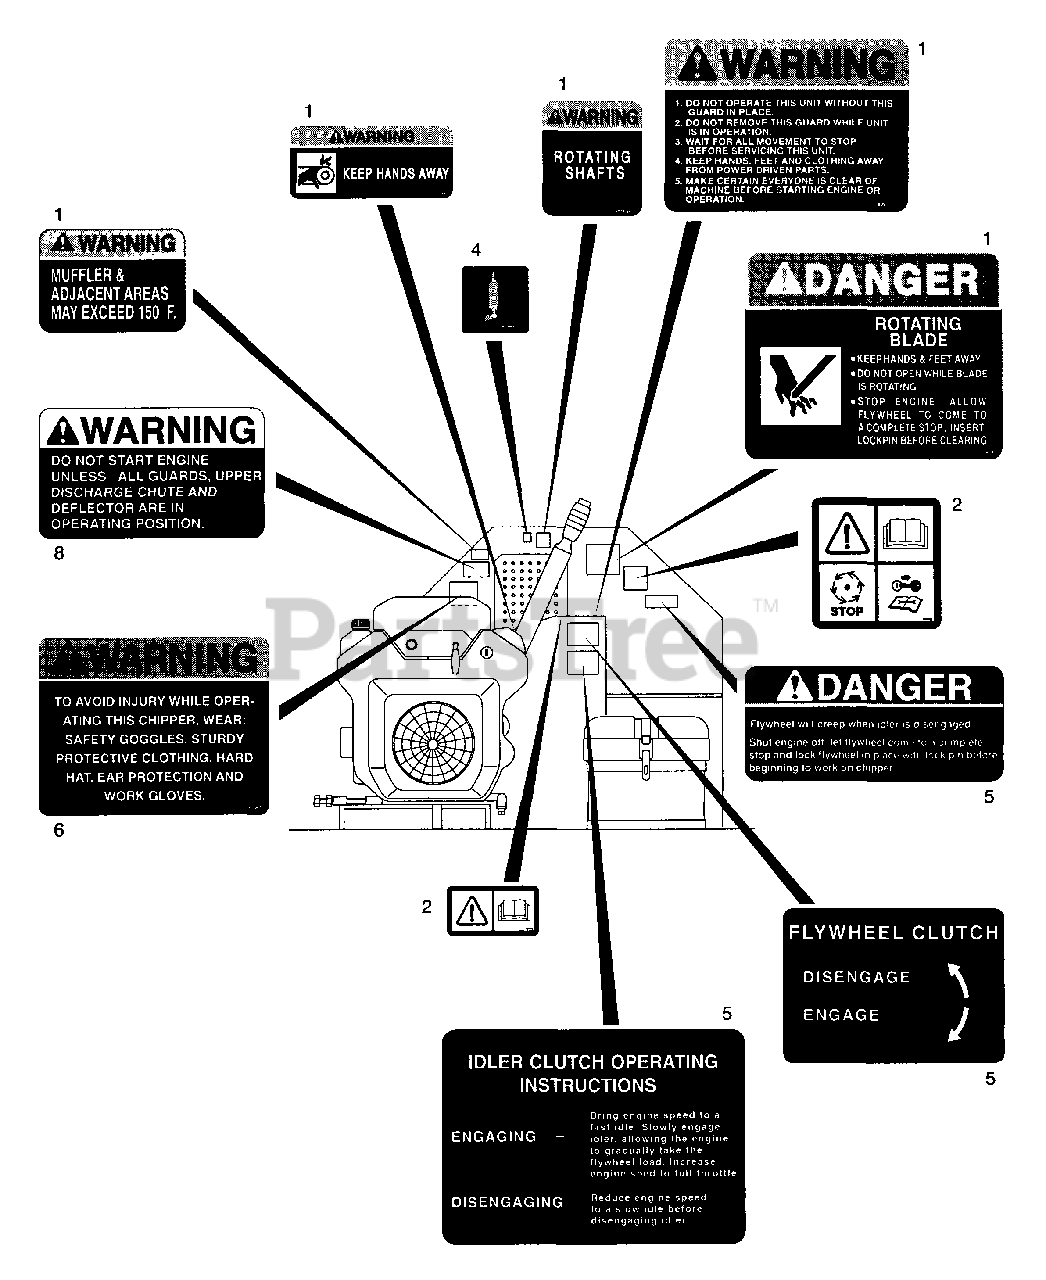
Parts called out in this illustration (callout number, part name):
1	Decal Set, Large Chippers
2	Decal Set, Chipper CE
4	Decal Set, Chipper Black & White
5	Decal Set, 210
6	Decal, Warning Protective
8	Decal, Warning, Start Engine
